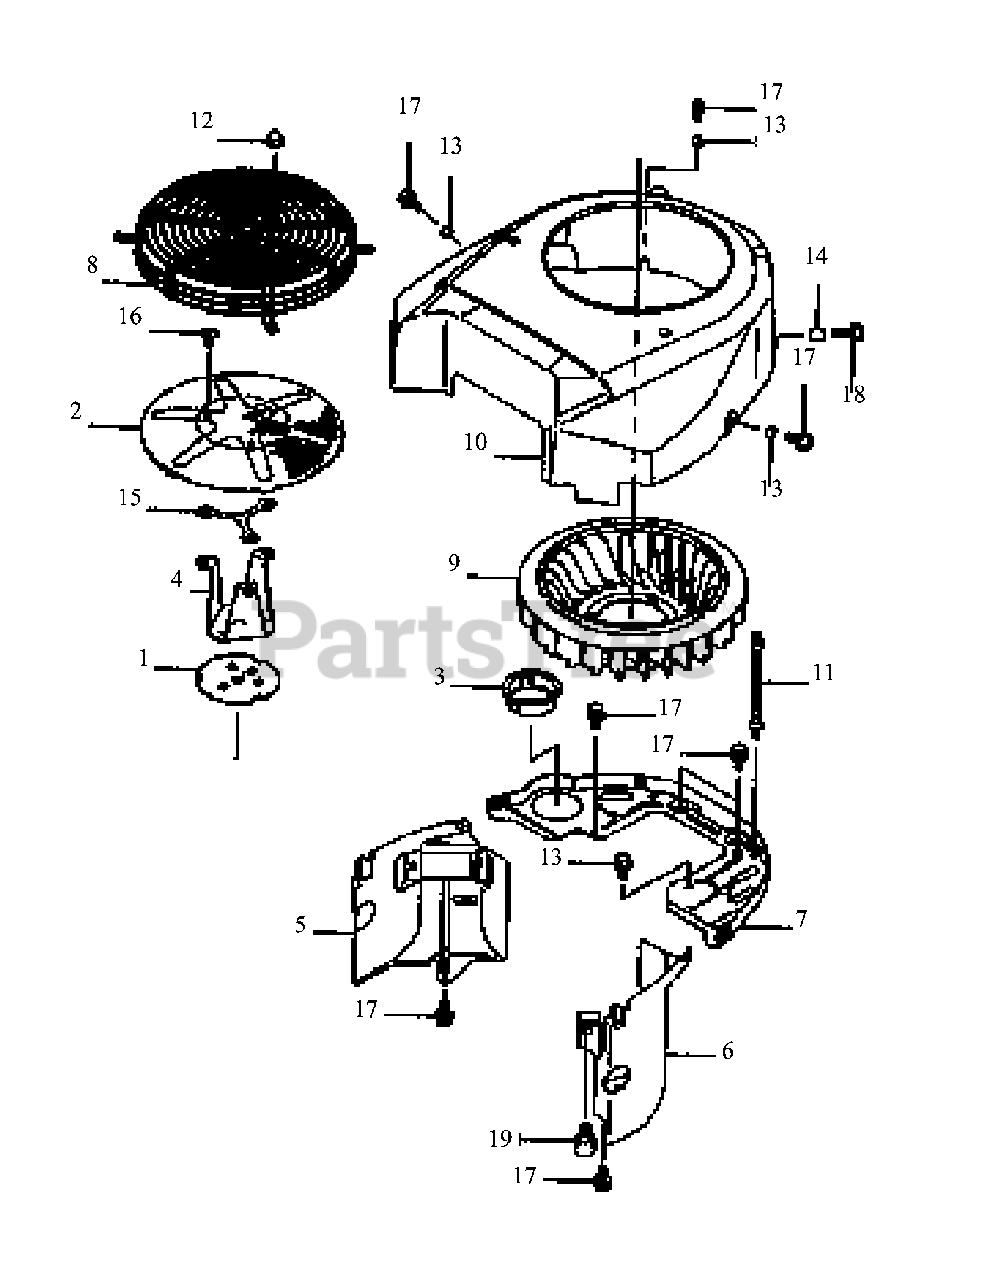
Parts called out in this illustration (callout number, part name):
4	Bracket-Comp
5	Shroud-Engine
6	Shroud-Engine
7	Shroud-Engine
13	Spacer 6.2 x 7.9 x5
14	Spacer 6.5x7.9x10.5
15	Spacer
16	Bolt, 6 x 10 mm
